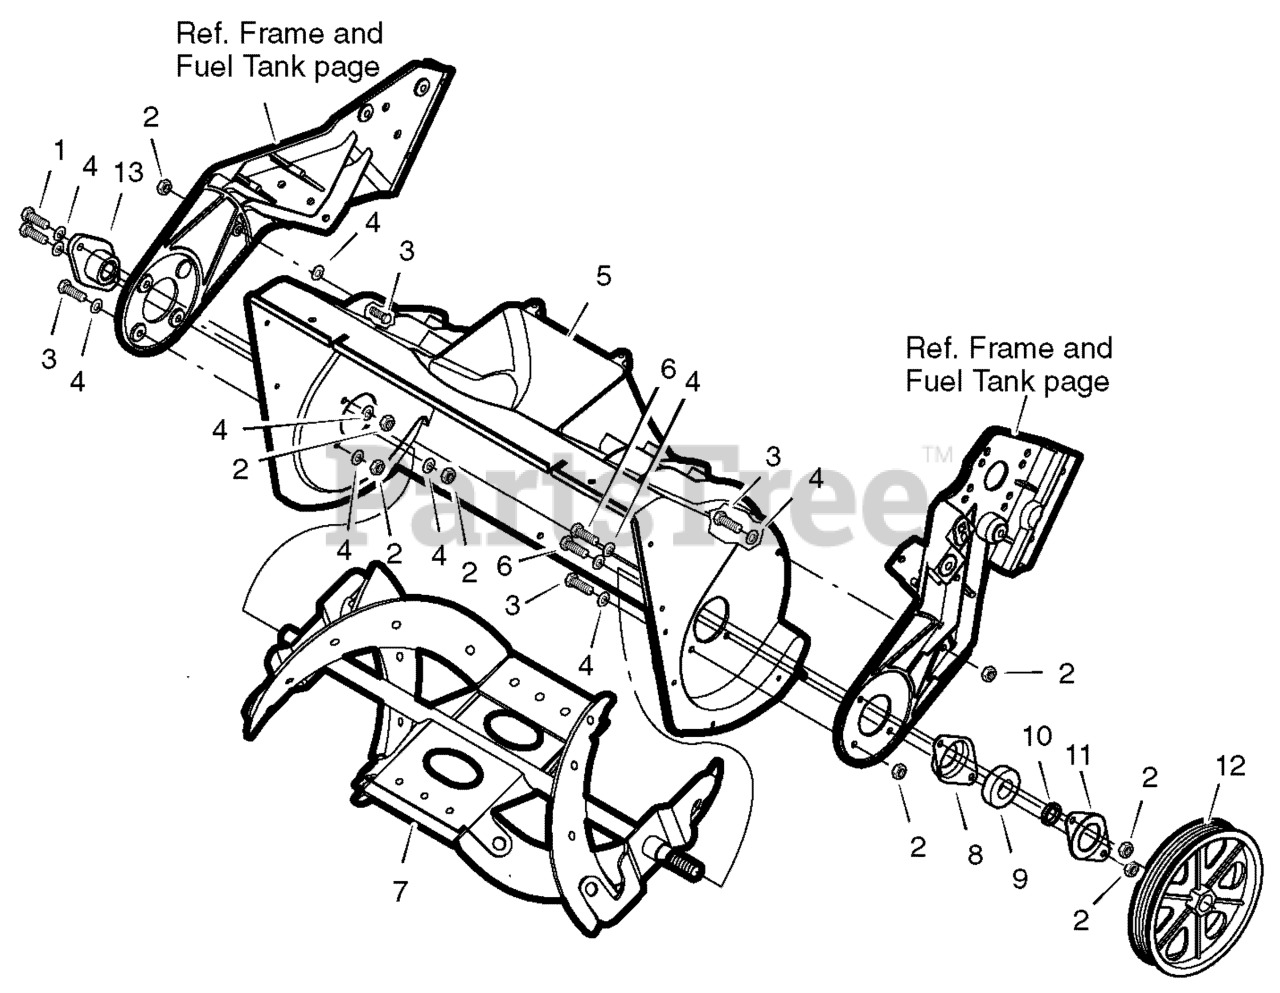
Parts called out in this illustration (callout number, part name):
1	Screw 1/4-20 x 1.00
2	Nut, Hex 1/4-20
3	Screw, 1/4-20 x .75
4	Washer, Flat
5	Housing Assy, Auger
6	Screw, 1/4-20 x .63
7	Auger Assembly, 22"
8	Retainer, Bearing
9	Bearing
10	Sleeve, Spacer
11	Plate, Bearing Retainer
12	Pulley, Auger Drive V6
13	Bearing, Flange
